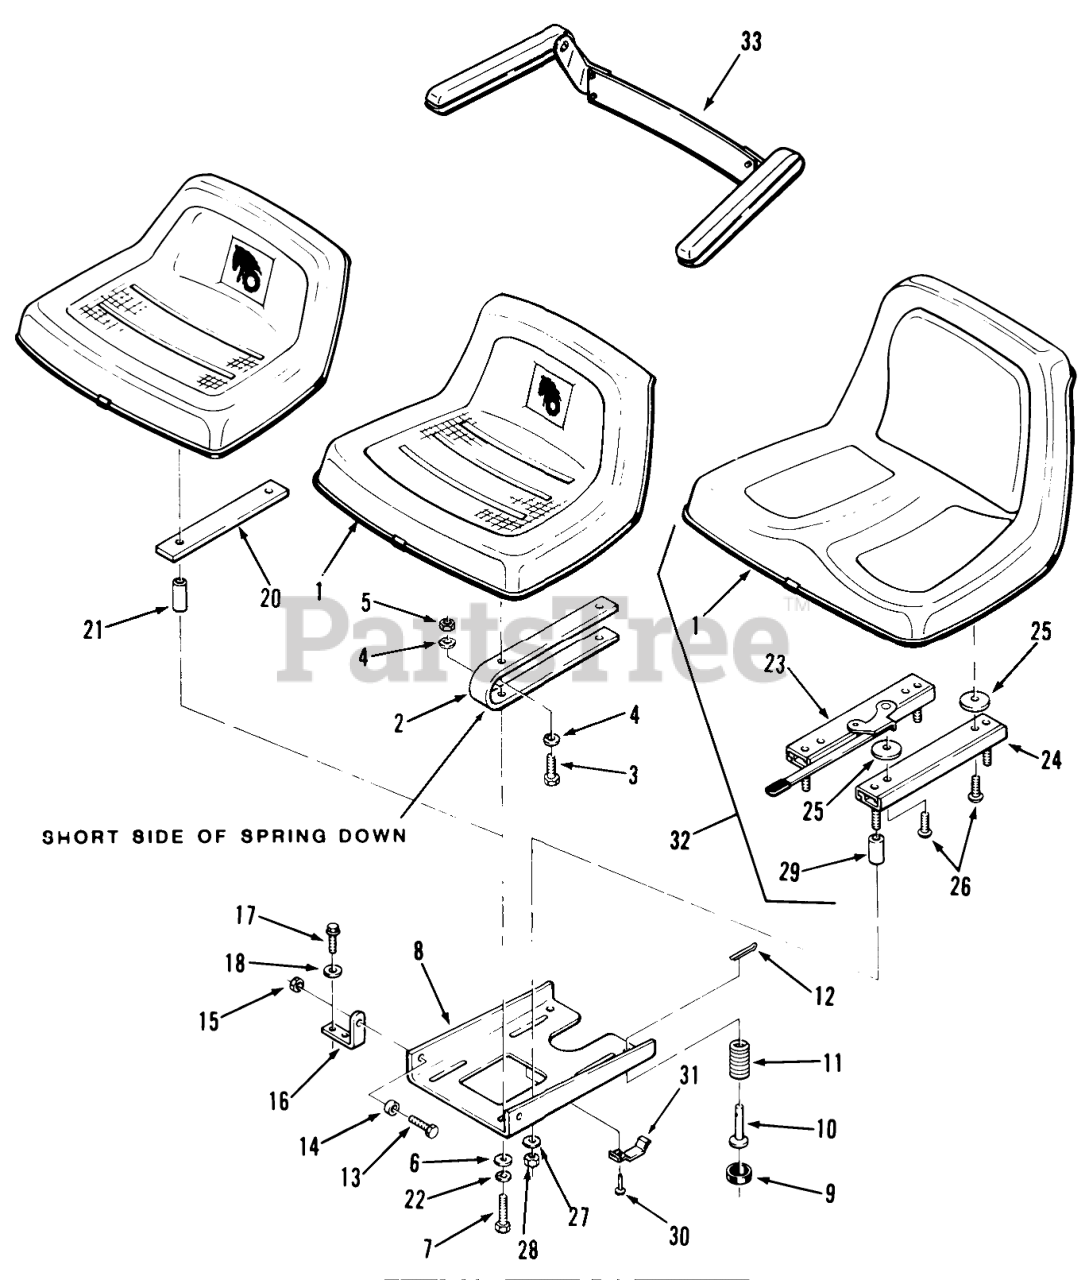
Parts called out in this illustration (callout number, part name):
1	Seat
1	Seat 312, 414
2	Seat Spring
3	Bolt
4	Lockwasher
5	Nut
6	Collar
7	HHCS
7	Pin-Cotter
8	PLATE SEAT PIVOT B
11	SPRING
12	Cotter Pin
13	HHCS
14	BUSHING
15	Nut
16	BRACKET-PIVOT
17	Bolt
18	WASHER 5/16 SAE
20	BAR SEAT SUPPORT B
21	SPACER SEAT B
22	Lockwasher
23	ADJUSTER-SEAT RH
24	ADJUSTER-SEAT LH
25	SPACER-NYLON
26	Screw
27	Collar
28	Nut
29	SPACER
30	RIVET
31	SPRING SWITCH
32	Deluxe Seat Assy (includes items 1, 23, 24, 25, 26 & 29)
33	KIT-ARMREST
